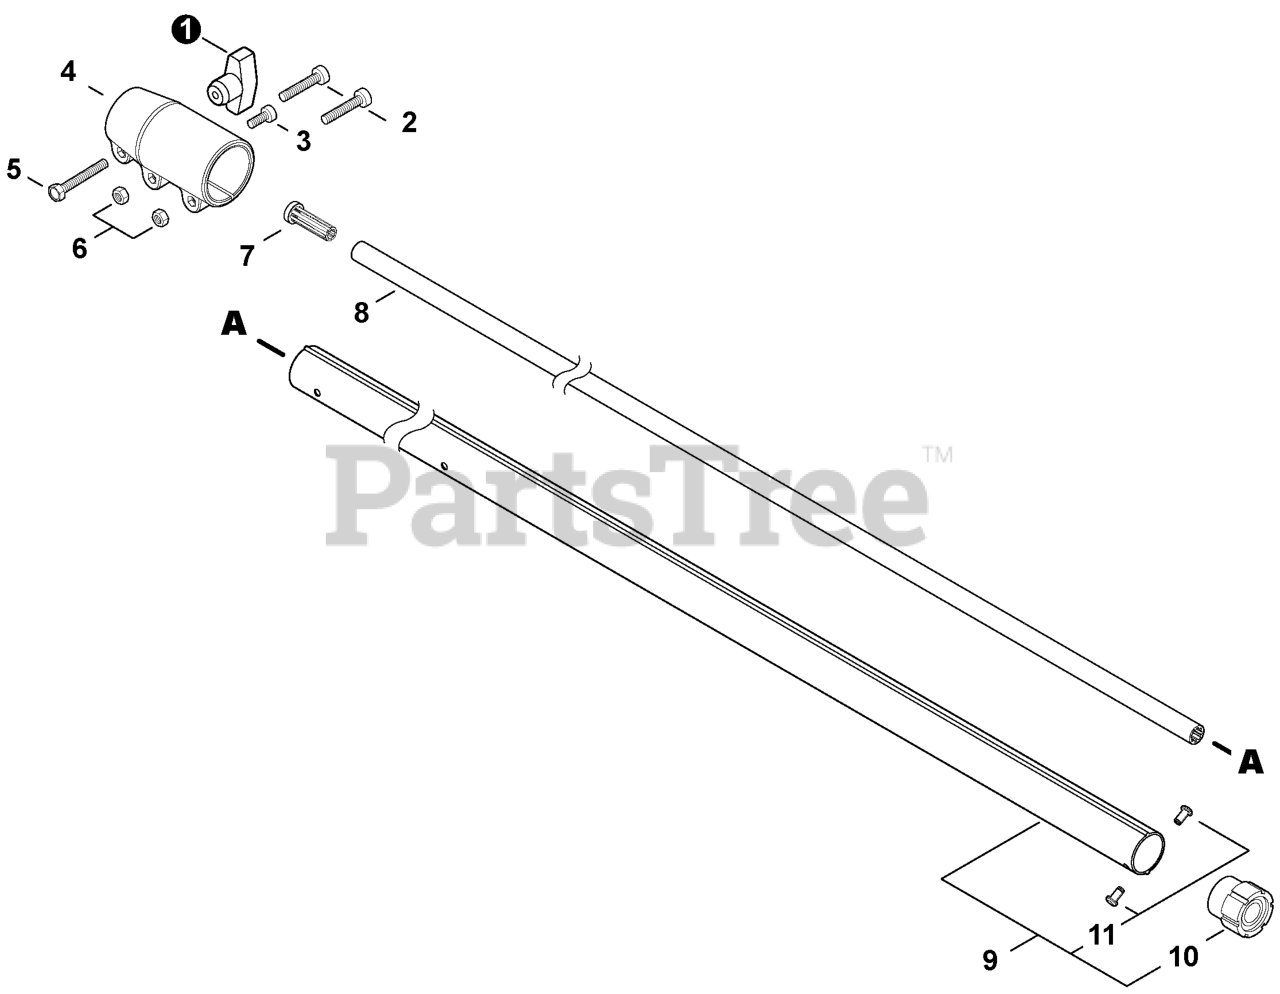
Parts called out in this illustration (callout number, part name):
1	THUMBSCREW
2	BOLT, TORX 5x20
3	BOLT, TORX 5x12
4	COUPLING, MAIN PIPE
5	BOLT 6x25
8	DRIVESHAFT - UPPER
9	MAIN PIPE ASSY - BLACK
10	HOLDER ASSY, BEARING
